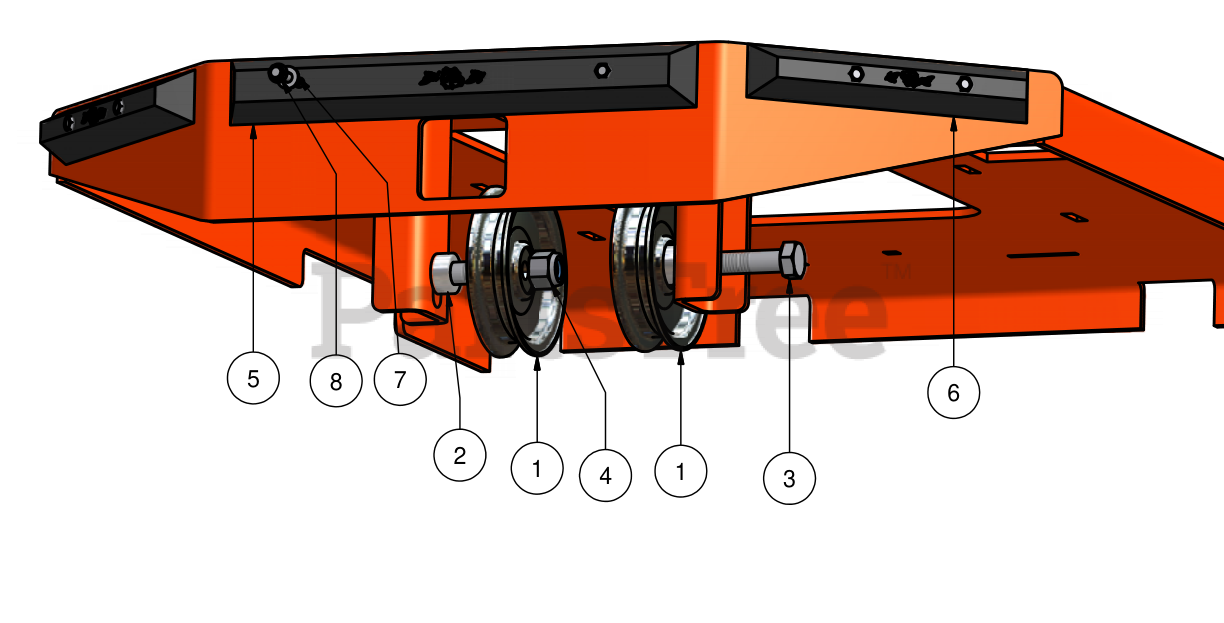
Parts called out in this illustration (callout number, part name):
1	5" V Idler Pulley
2	5/8" x 1/2" Collar Spacer
3	5/8" x 2 1/2" Bolt
4	5/8" Nylock Nut
5	14" Bumper
7	1/4" Flat Washer
8	1/4" x 1 1/2" Self Tapping Screw
